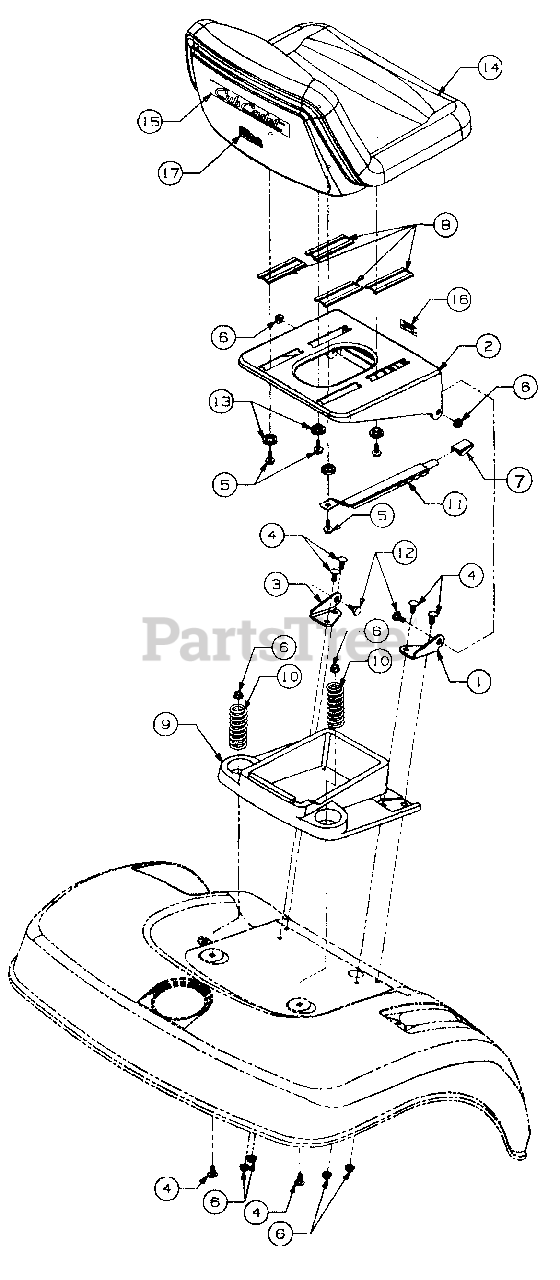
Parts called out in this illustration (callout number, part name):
1	Bracket, RH Seat Pivot
2	Seat, Base
3	Bracket, LH Seat Pivot
4	Bolt, Carriage, 5/16-18 x .75
5	Screw, Hx Wsh Hd Tap 5/16-18 x .75
6	Nut, Hex Flange Lock, 5/16-18
7	Knob, Seat Adjuster
8	Slide, Seat
9	Tray, Tool
10	Spring, Comp, 1.9 OD x 2.4 Lg
11	Adjuster, Seat
12	Bolt, Shoulder
13	Spacer, Shoulder
14	Seat, High Back
15	Graphic, Seat Back Script
16	Graphic, Seat Adjuster
17	Graphic, Made in USA
